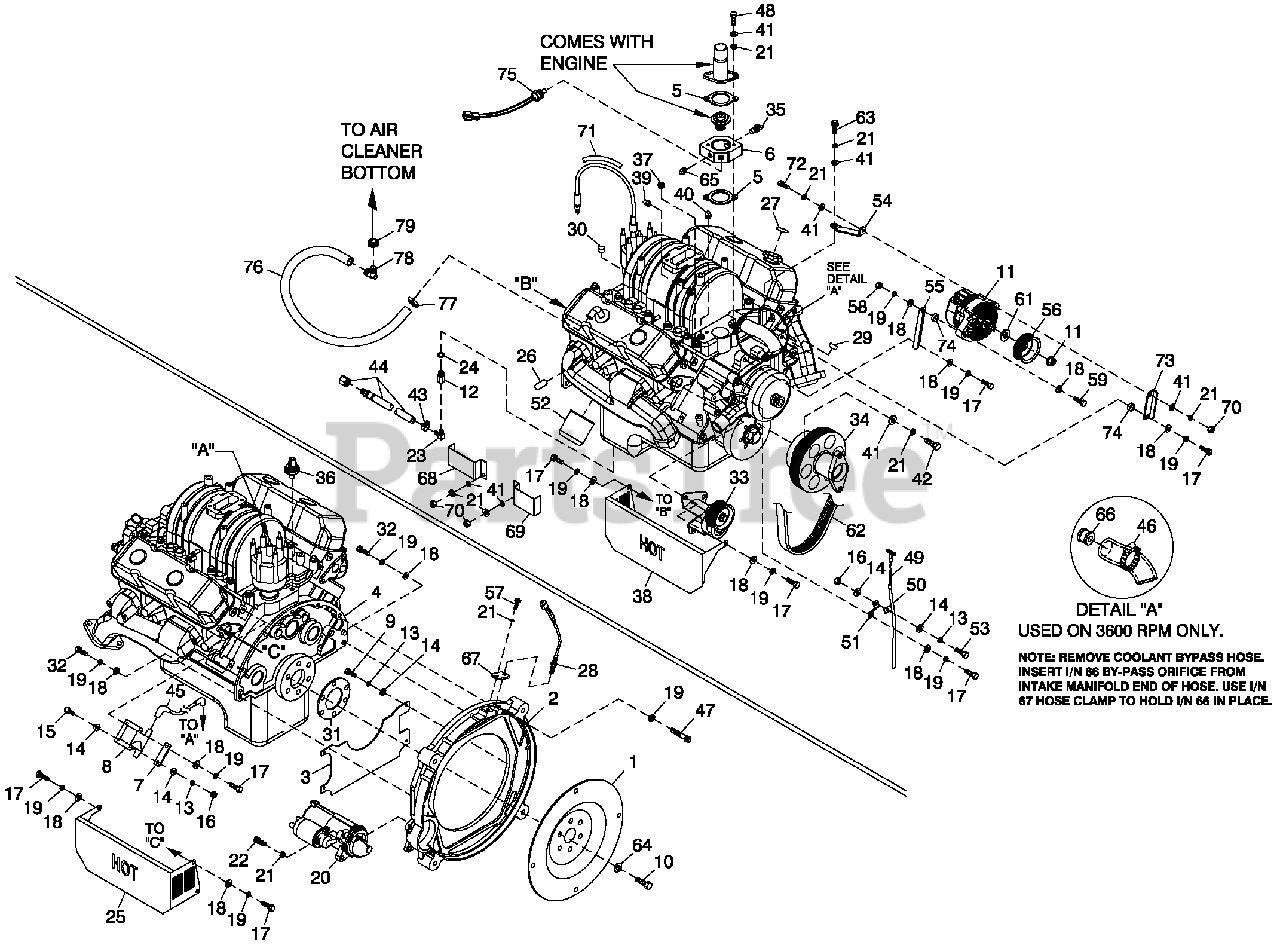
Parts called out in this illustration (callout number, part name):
1	FLEXPLATE HSB 3.9L CHRYSLER (1800RPM)
2	ENG ADAPTER MACH 3.9L HSB NSPS
3	COVER FLYWHEEL ACCESS
4	ENGINE INSERTED VALVE 3.9L (3600 RPM)
5	GASKET THERMOSTAT ADAPTOR
6	MACH THERM ADAPTOR 3.9L CHRY
7	BRACKET IGNITION COIL
8	COIL IGNITION 3.9L CHRYSLER
9	SCREW HHC M6-1.0 X 16 G8.8
10	BOLT 7/16-20 X 7/8
11	D.C. ALTERNATOR W/OUT PULLEY
12	ADP OIL DRN 1/2-20
13	WASHER LOCK M6-1/4
14	WASHER FLAT 1/4-M6 ZINC
15	SCREW HHC M6-1.0 X 35 G8.8 BLK
16	NUT HEX M6 X 1.0 G8 YEL CHR
17	SCREW HHC 3/8-16 X 1 G8
18	WASHER FLAT 3/8-M10 ZINC
19	WASHER LOCK 3/8
20	STARTER 12V
21	WASHER LOCK M8-5/16
22	SCREW SHC M8-1.25 X 30 G12.9
23	BARBED EL 90 3/8 NPT X 3/8
24	WASHER NYLON .50 X .87 X .06
25	HEAT SHEILD L/H SIDE
26	CAP VINYL 1/4" ID X 1" DP BLK
27	DECAL REFER TO OWNERS MANUAL
28	ASSY MAGPICKUP (3/8-24 MALE)
29	PLUG EXPANSION 21/32" O.D. (WATER PUMP) (QTY 1)
30	PLUG EXPANSION 14.1 O.D. (INJCTOR HOLE) (QTY 6)
31	SPACER FLEX PLATE 3.9L C4 CPL (3600 RPM)
32	SCREW SHC M10-1.5 X 35 G12.9
33	TENSIONER W/BRACKET
34	PULLEY CRANKSHAFT (3600 RPM)
35	SENSOR HI COOLANT SHUTDOWN
36	SWITCH OIL PRESSURE 10 PSI 2 POL
37	PLUG STD PIPE 1/8 SOCKET HEAD
38	HEAT SHIELD R/H SIDE
39	PLUG PIPE 1/4 CSK W/ VIBRA SL
40	PLUG STD PIPE 3/8 COUNTERSUNK
41	WASHER FLAT 5/16-M8 ZINC
42	SCREW HHC 5/16-18 X 1-1/2 G5 (3600 RPM)
43	HOSE CLAMP BAND 5/8"
44	HOSE DRAIN ASSY 28"
45	CABLE IGN COIL 3.9L CHRYSLER
46	CLAMP HOSE #16 .87-1.50 (3600 RPM)
47	SCREW SHC 3/8-16 X 1.25 G8.8 Z
48	SCREW HHC 5/16-18 X 2 G5
49	TUBE DIPSTICK 3.9L CHRYSLER
50	DIPSTICK OIL LEVEL 3.9L CHRYSLER
51	BRACKET DIPSTICK TUBE
52	OIL FILTER 3.9L CHRYSLER
53	SCREW HHC M6-1.0 X 20 G8.8
54	BRKT L/H SIDE D.C. ALTERNATOR
55	BRKT R/H SIDE D.C. ALTERNATOR
56	PULLEY 132 OD DC ALTERNATOR (3600 RPM)
57	SCREW HHC M8-1.25 X 20 G8.8
58	NUT HEX 3/8-16 STEEL
59	SCREW HHC 3/8-16 X 1-3/4 G5
61	SPACER DC ALTERNATOR PULLEY
62	SERPENTINE BELT (60.5")
63	SCREW HHC 5/16-18 X 2-1/2 G5
64	WASHER FLAT .45 X 1.00
65	PLUG STD PIPE 3/8 STEEL SQ HD
66	BYPASS ORIFICE 3.9L CHRYSLER (3600 RPM)
67	PLATE MAG PICK-UP ADAPTOR
68	SHIELD HT RR (C4 3600 RPM ONLY) (BOTH SIDES)
69	SHIELD HT FRT (C4 3600 RPM ONLY) (BOTH SIDES)
70	NUT HEX M8-1.25 G8 CLEAR ZINC (C4 3600 RPM ONLY)
71	REFLEX WRAP 13MM X 153.3MM (C4 3600 RPM ONLY)
72	SCREW HHC M8-1.25 X 45 G8.8
73	BRKT L/H SIDE DC ALTERNATOR
74	SPACER .41 X .75 X .18 AL
75	ASSY WATER LEVEL SENSOR C/E PL
76	HOSE 3/4 ID SAE-30R2 (17” LG)
77	CLAMP HOSE #8 .53-1.00
78	BARBED EL 90 3/4 PLASTIC
79	GROMMET
